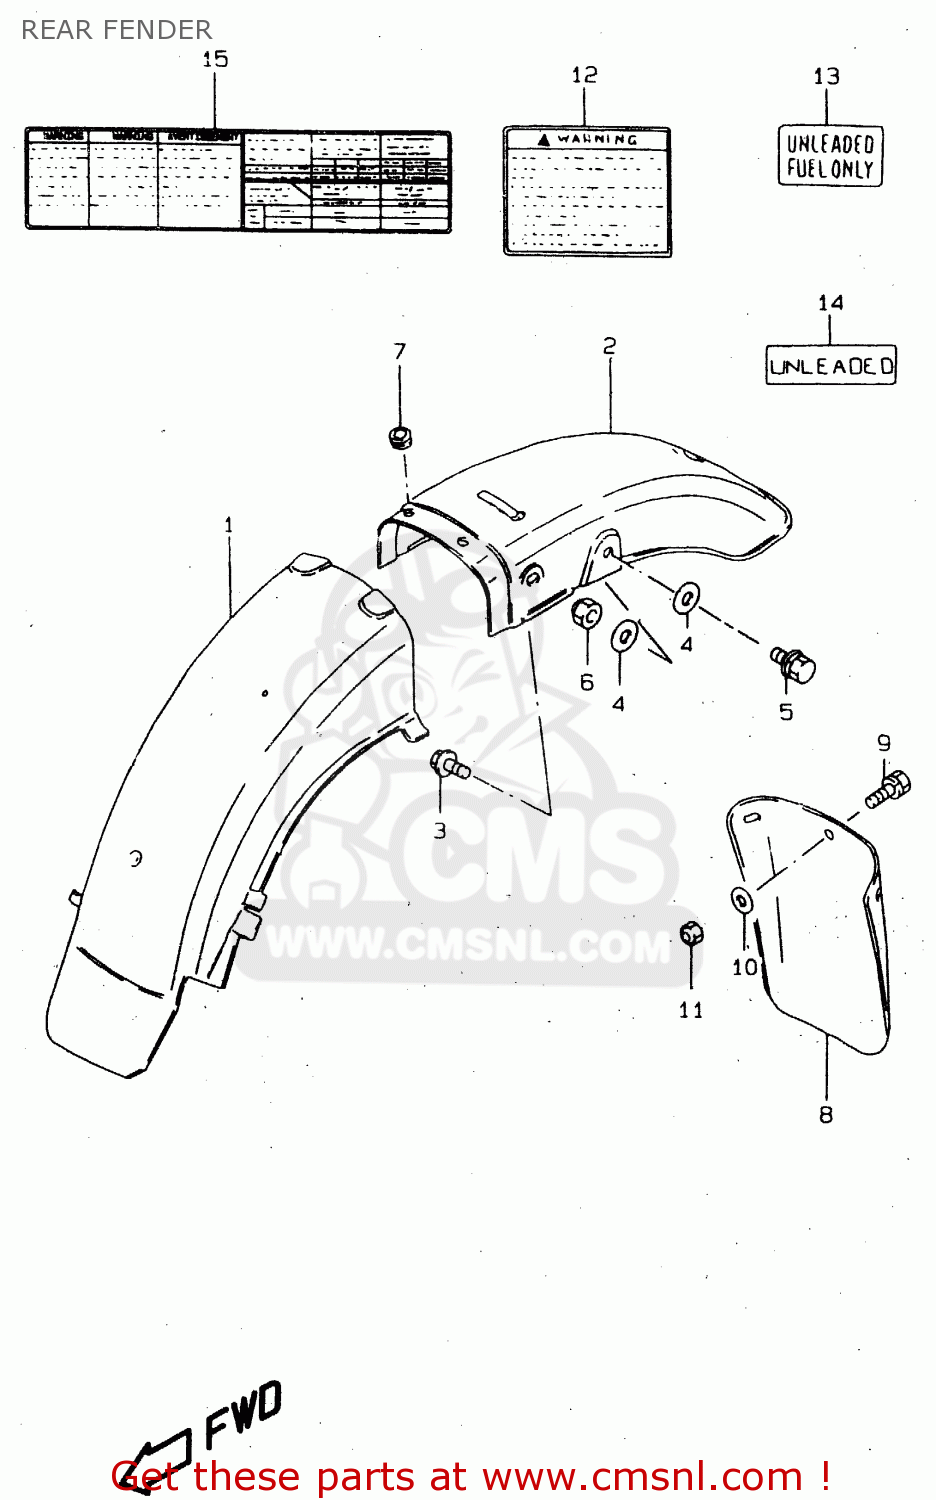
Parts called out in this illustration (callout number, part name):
1	BODY,FR
2	FENDER,RR
3	BOLT
4	WASHER
5	BOLT
6	NUT
7	CUSHION
8	FLAP,RR FENDER MUD
9	BOLT
10	WASHER(6.5X18X1.6)
11	NUT 6MM
12	LABEL,WARNING
13	LABEL,FUEL CAUTION
14	LABEL,CAUTION
15	LABEL, TIRE INFORMATION
16	MANUAL, OWNER'S
